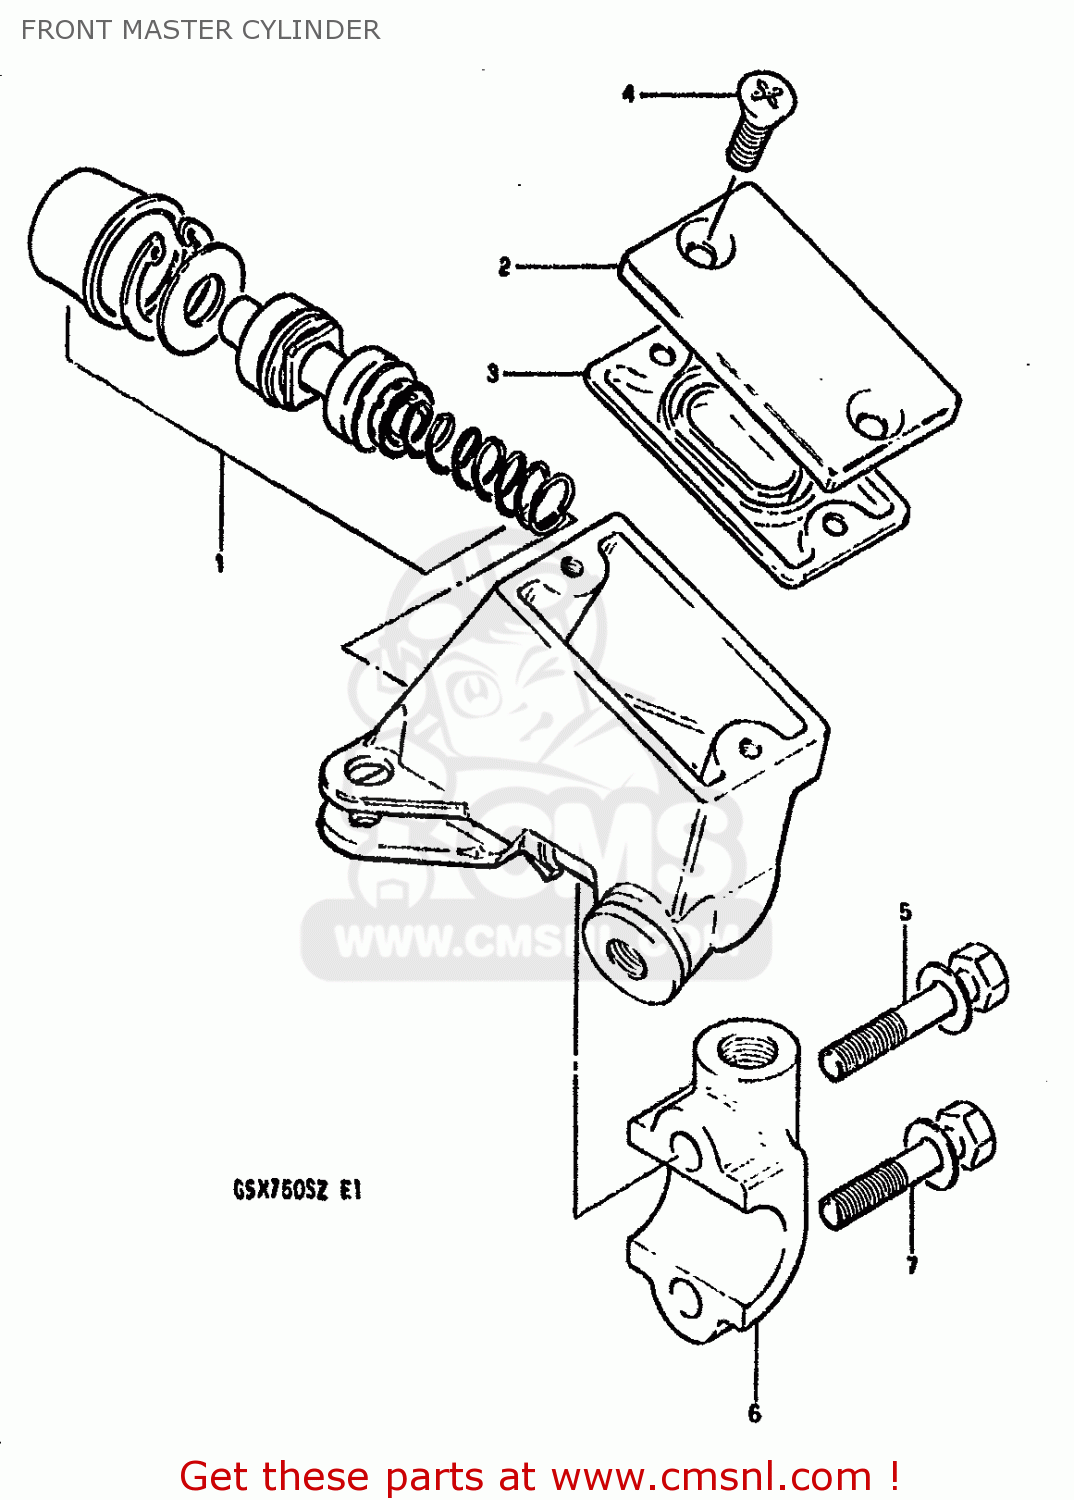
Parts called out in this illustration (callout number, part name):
1	PISTON & CUP SET
2	CAP
3	DIAPHRAGM,MASTER CYLINDER
4	SCREW,RESERVOIR CAP
5	BOLT,MASTER CYLINDER H
6	HOLDER
7	BOLT,MASTER CYLINDER H
